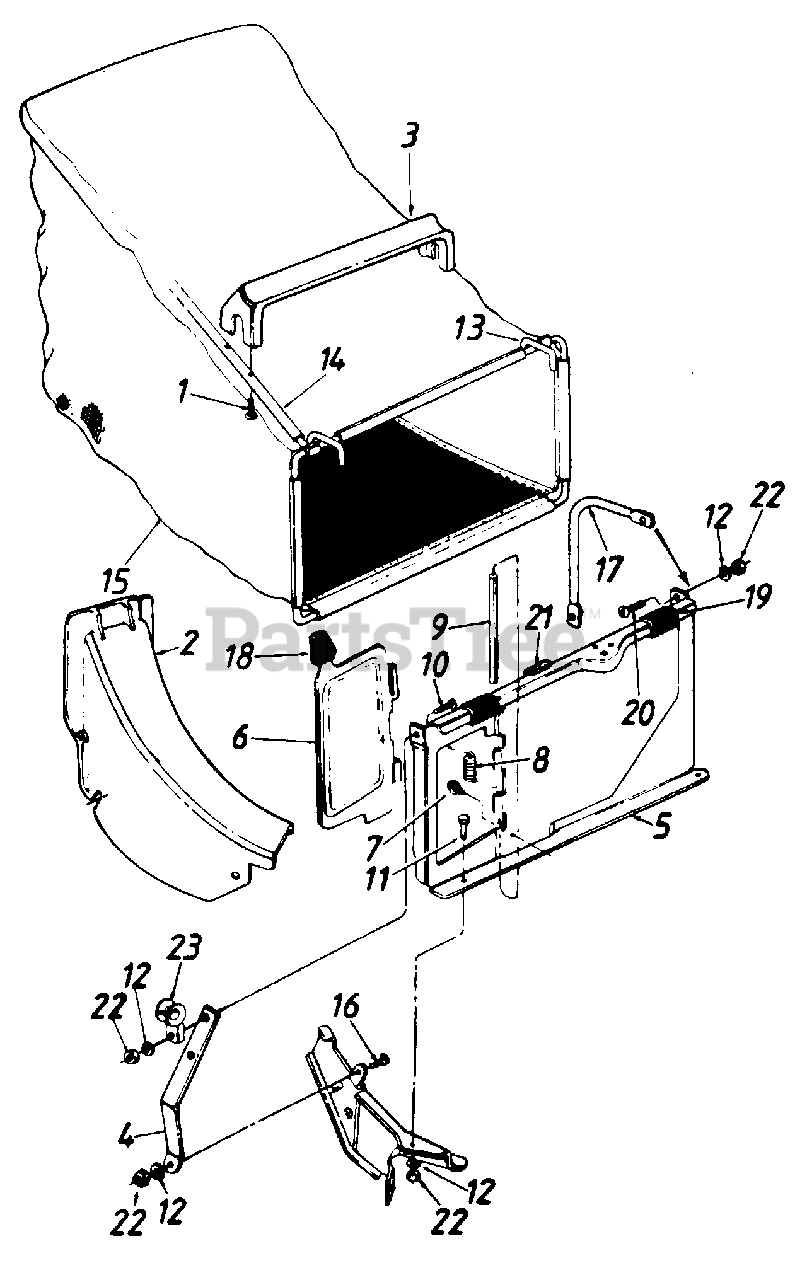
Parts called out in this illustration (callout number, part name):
1	Hex AB-Tap Scr. #12 x 1.25' Lg.
2	Rear Discharge Chute Ass'y.
3	Bag Handle
7	Hex B-Tap Scr. #10 x 38n
8	Torsion Spring
9	Pivot Pin
10	Truss Mach. Scr. 1/4-20 x 3/4" Lg.
11	Hex Bolt 1/4-20 x 50n Lg.
12	L-Wash. 1/4" I.D.
15	21n Rear Discharge Grass Bag
16	Hex Bolt 1/4-20 x .62" Lg.
17	Catcher Panel Support Arm
18	Door Grip
19	Panel Clip
20	Truss Mach. Scr. 1/4-20 x .62" Lg.
21	Foam Strip
22	Hex Nut 1/4-20 Thd.
23	Rope Guide
